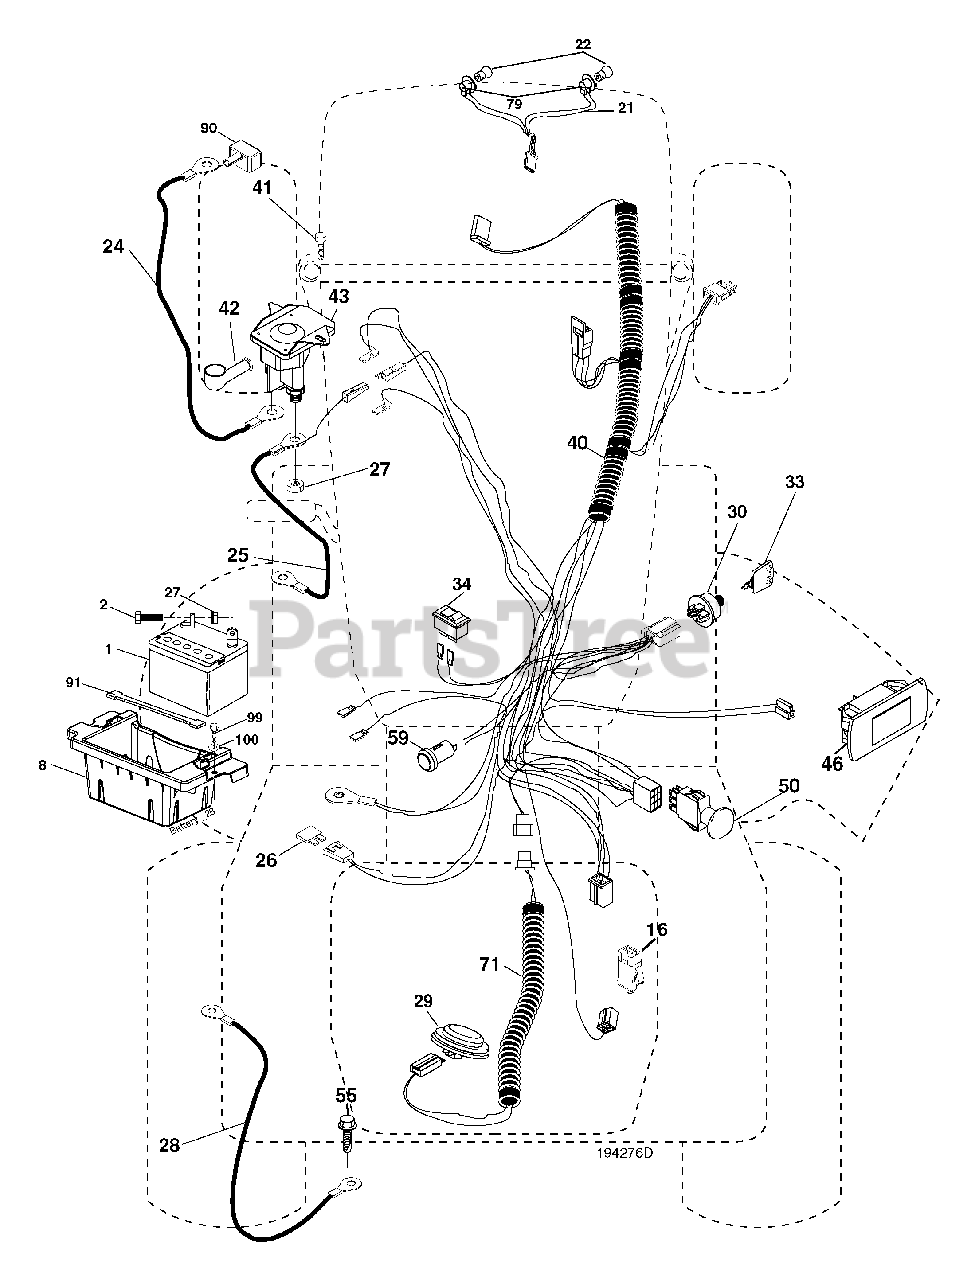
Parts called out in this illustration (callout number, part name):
1	Battery
2	Bolt Hex Head 1/4-20 x 3/4
8	Box Battery
16	Switch Interlock Push-In
21	Harness Socket Light W/4152J
22	Bulb Light
24	Cable Battery
25	Cable Start Red
26	Fuse
27	Nut Keps Hex 1/4-20 unc
28	Cable, Ground
29	Switch, Seat
30	Switch, Ignition
33	Key, Ignition
34	Switch Light / Reset
40	Harness Ignition
41	Screw Thd Cut 1/4-20 x 1/2
42	Cover, Terminal
43	Solenoid
46	Gauge Hourmeter
50	Switch, PTO
55	Screw Thdrol 5/16-18 x 3/4 TYTT
59	Outlet 12-Volt
71	Harness Ign. Dash
79	Bulbholder Asm. Incan Descent
90	Cover Terminal Battery
91	Strap Battery Mount Front
99	Screw Hexwsh Thdrol 1/4-20 x 3/4
100	Washer 9/32 x 7/8 x 16 Ga.
